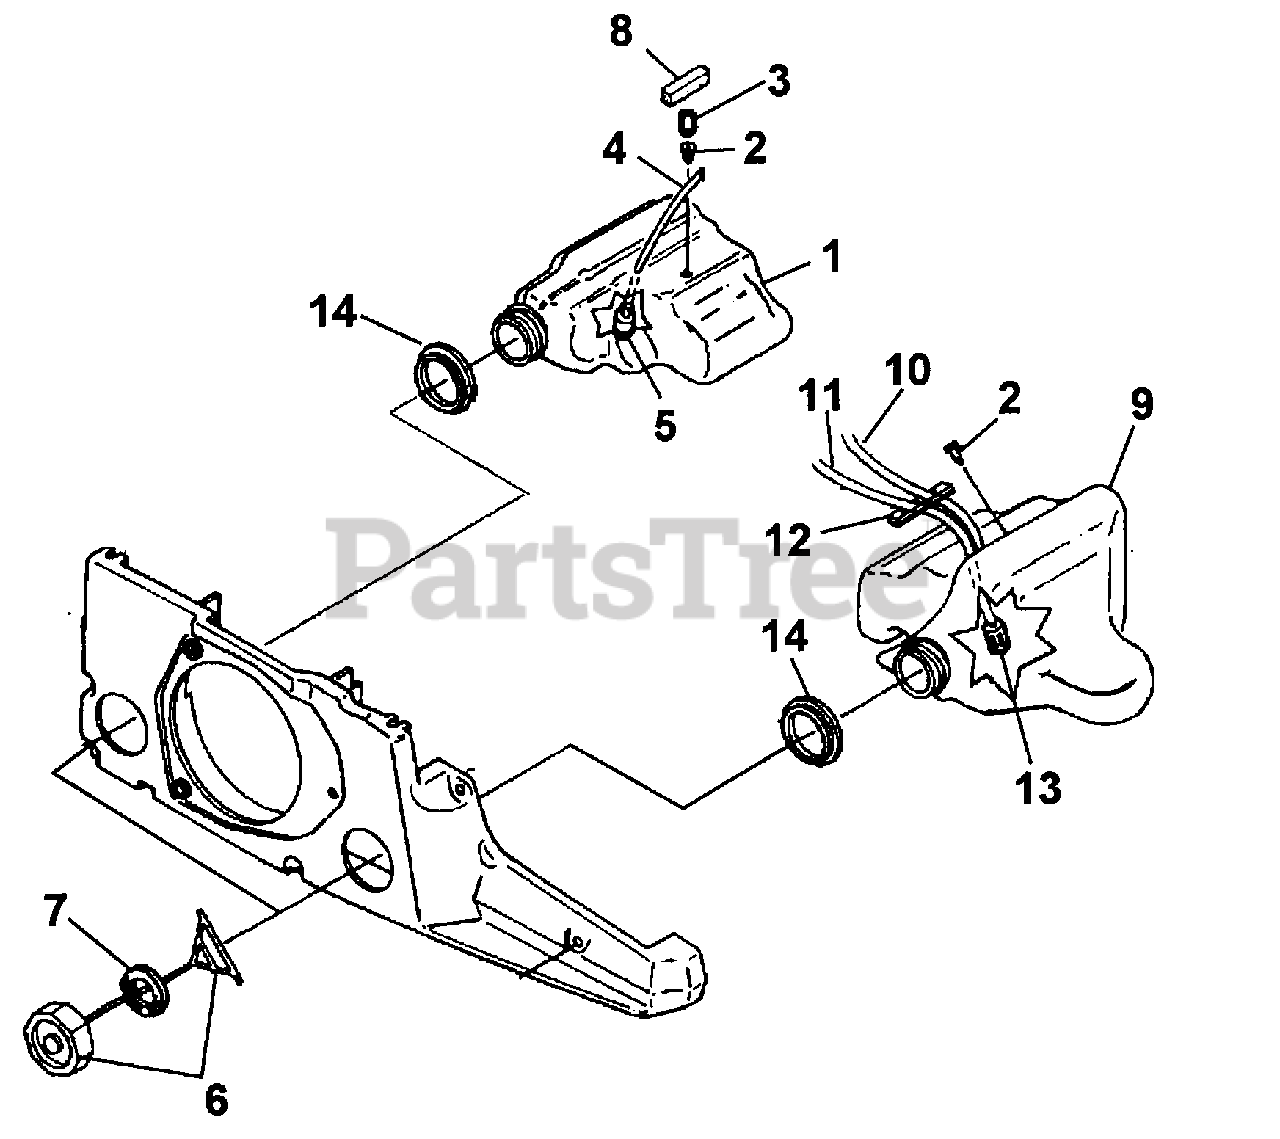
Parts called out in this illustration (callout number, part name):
1	OIL TANK ASSY.
2	VALVE-Check
3	PIN-Spirol
4	TUBING-Rubber (7 1/4")
5	FILTER-Oil
6	CAP-Tank
7	GASKET-Fuel Cap
8	FILTER-Oil Tank Valve
9	FUEL TANK ASSY.
10	TUBING-Rubber (5 1/4")
11	TUBING-Rubber (9")
12	FILTER-Foam
13	FILTER-Fuel
14	SAWDUST SEAL
